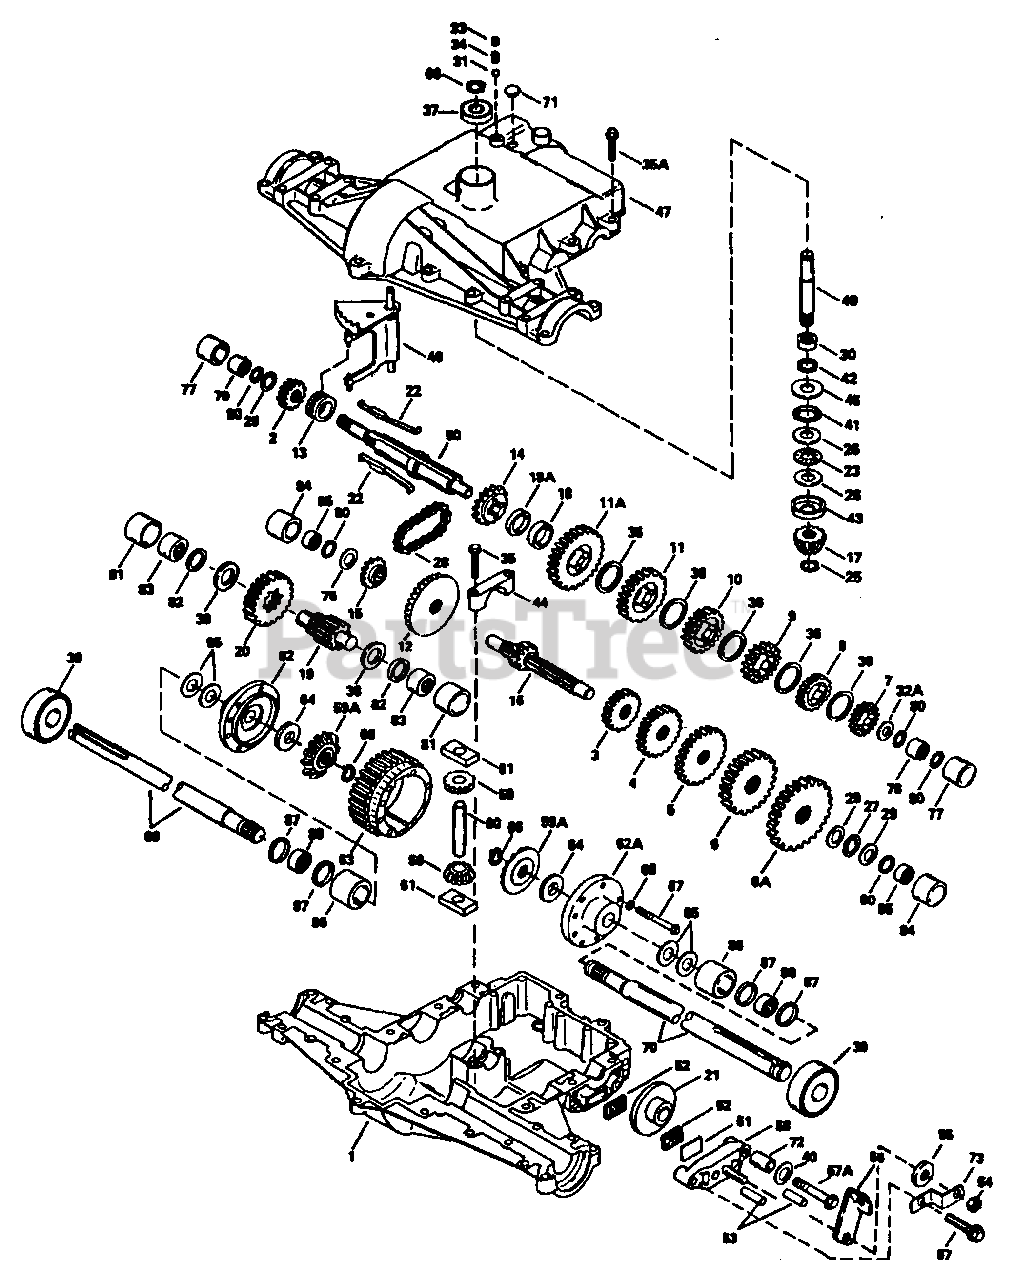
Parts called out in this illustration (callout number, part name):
1	Case, Transaxle
2	Gear, Spur (15 teeth)
3	Gear, Spur (12 teeth)
4	Gear, Spur (18 teeth)
5	Gear, Spur (25 teeth)
6	Gear, Spur (28 teeth)
6A	Gear, Spur (31 teeth)
7	Gear, Spur (19 teeth)
8	Gear, Spur (22 teeth)
9	Gear, Spur (25 teeth)
10	Gear, Spur (32 teeth)
11	Gear, Spur (37 teeth)
11A	Gear, Spur (41 teeth)
12	Gear, Bevel (33 teeth)
13	Collar, Shift
14	Sprocket (18 teeth)
15	Sprocket (9 teeth)
16	Shaft, Counter (w/9 tooth gear)
17	Bevel Pinion, Input (13 teeth)
18	Spacer, Neutral (.350/.340 thick)
18A	Spacer, Neutral (.276/.268 thick)
19	Shaft, Output (9 teeth)
20	Gear, Output (35 teeth)
21	Disk, Brake
23	Bearing, Thrust
25	Ring, Retaining
26	Washer, Thrust
27	Bearing, Thrust
28	Chain, Roller (No. 41 chain, 24 links)
29	Washer, Thrust
30	Bearing, Needle
31	Ball, Steel
32A	Washer, Thrust
33	Screw, Set, 3/8-16 x 3/8
35	Screw, Flanged hex hd. thread-forming, 1/4-20 x 1-1/4
35A	Screw, Hex hd. thread forming, 5/16-18 x 1-1/4
36	Washer, Thrust
37	Bearing, Ball
38	Washer, Thrust
39	Bearing, Ball
40	Washer, Flat
43	Washer, Cupped
44	Cap, Bearing
45	Washer, Flat
47	Cover, Transaxle
48	Rod & Fork Assy., Shift
49	Shaft, Input
50	Shaft, Brake (4 Keyed)
51	Plate, Brake pad
54	Locknut, 5/16-24
55	Washer, Flat
56	Lever, Brake
57	Screw, Flanged hex hd. thread-forming, 1/4-20 x 1-1/4
57A	Screw, Flanged hex hd. thread-forming, 1/4-20 x 2-1/4
58	Holder, Brake pad
59	Pinion, Differential bevel
59A	Gear, Bevel
61	Block, Drive
62	Carrier, Differential (Threaded holes)
62A	Carrier, Differential
63	Gear, Ring (31 teeth)
65	Washer, Thrust
67	Screw, Hex hd., 1/4-20 x 2-1/4
68	Lockwasher, 1/4"
69	Axle (12-5/16" long)
70	Axle (16-3/16" long)
71	Plug, Hex hd., 9/16-18 thread
73	Bracket, Brake lever
77	Sleeve (stepped)
78	Bearing, Needle
79	Bearing, Needle (capped)
81	Sleeve (stepped)
82	Ring, Square cut
83	Bearing, Needle (capped)
84	Sleeve (stepped)
85	Bearing, Needle (capped)
86	Sleeve (stepped)
87	Ring, Square cut
88	Bearing, Needle
